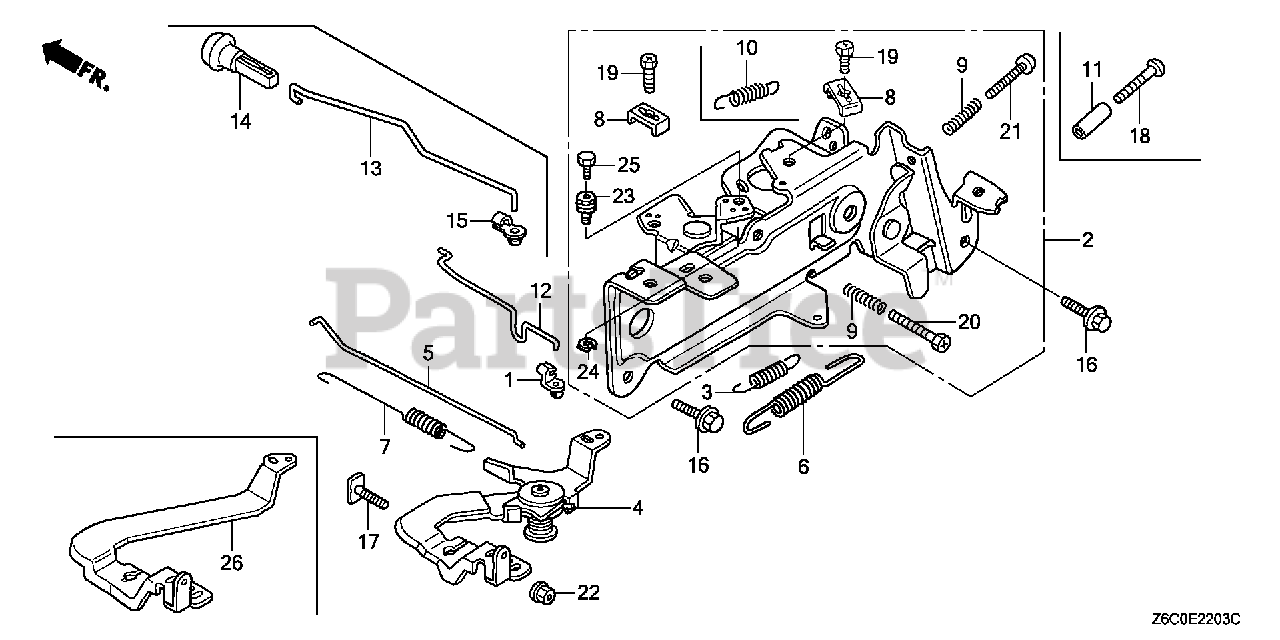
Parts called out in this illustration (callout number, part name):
1	JOINT, ROD
2	CONTROL ASSY. (AUTO THROTTLE)
3	SPRING, STARTER
4	ARM, GOVERNOR
5	ROD, GOVERNOR
6	SPRING, GOVERNOR (MANUAL)
7	SPRING, THROTTLE RETURN
8	HOLDER, CABLE
9	SPRING, CONTROL ADJUSTING
10	SPRING, CABLE RETURN
12	ROD, CHOKE CONTROL
16	BOLT, FLANGE (6X14) (CT200)
17	BOLT, GOVERNOR ARM
19	BOLT, RECESSED (5X16)
20	BOLT, RECESSED (5X25)
21	SCREW, PAN (5X35)
22	NUT, FLANGE (6MM)
23	HOLDER, WIRE
24	CIRCLIP (5MM)
25	BOLT, RECESSED (4X6)
